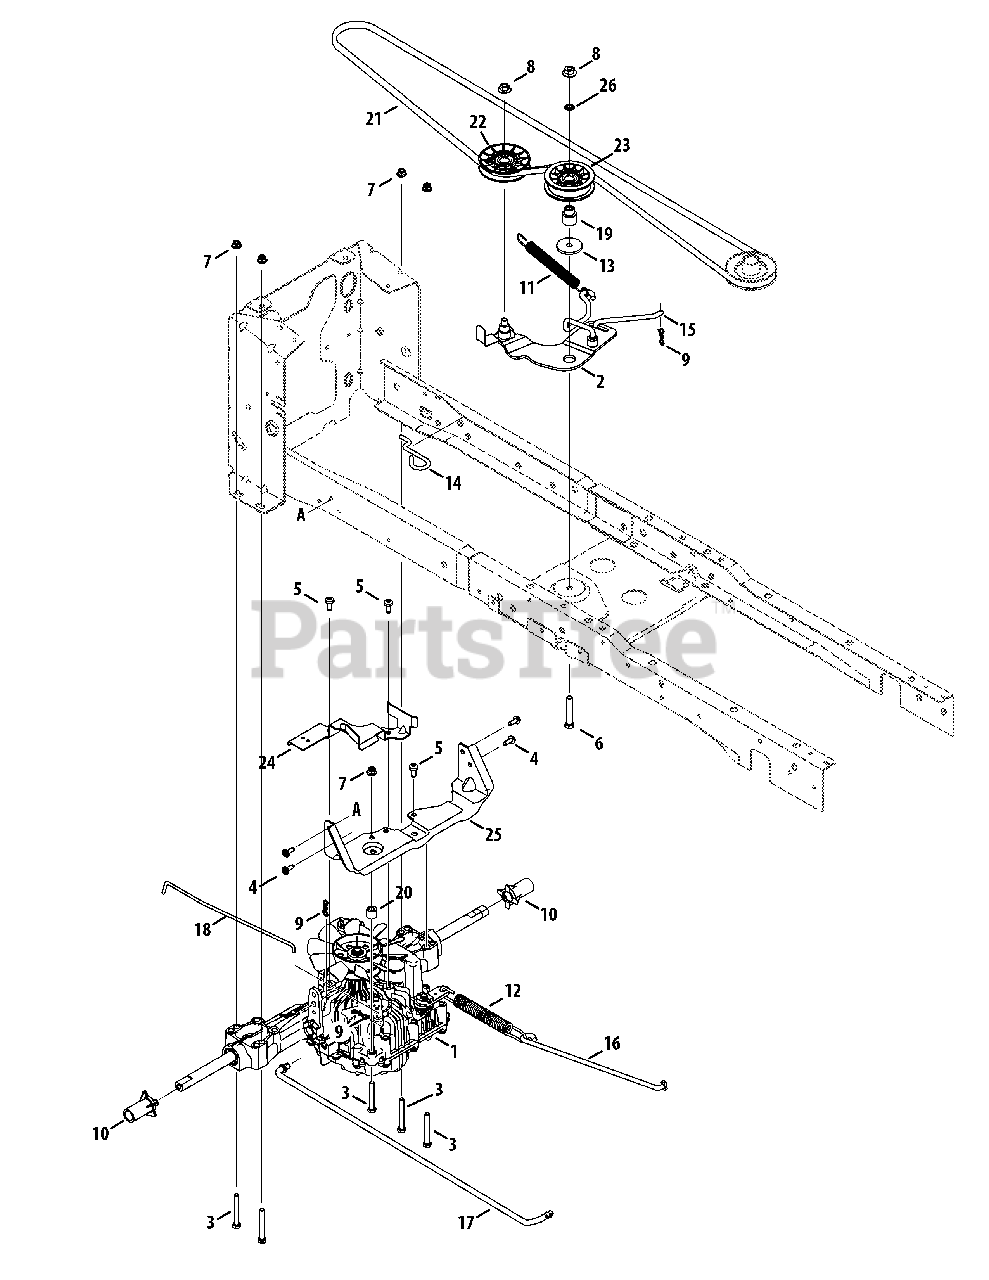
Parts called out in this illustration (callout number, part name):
1	Transmission Assembly
2	Idler bracket Assembly
3	Hex Screw, 5/16-18, 2.50, Gr5, Std
4	Screw, M6-1 x .625
5	Screw, Self-tapping, 5/16-18, 0.750
6	Hex Screw, 3/8-16, 2.25, Gr5
7	Nut, Flange Lock, 5/16-18, Nylon
8	Flange Lock Nut, 3/8-16
9	Pin, Cotter, Bow-Tie 72
10	Sleeve, .765 Id x 2.11
11	Spring, Extension, .790 Dia x 8.41
12	Spring, Extension, .90 Dia x 8.14
13	Shoulder Spacer, .884 x .190
14	Deck Spring Rod
15	Idler Link
16	Rod, Brake, Tuff Torq
17	Rod, Control, Tuff Torq
18	Rod, Transmission, Bypass
19	Shoulder Spacer
20	Spacer, .34 x .75 x .63
21	Belt, V-Type
22	Idler Pulley, 3.56 OD
23	Idler Pulley, 3.00 OD
24	Belt Keeper Bracket
25	Transmission Bracket
26	Speed Nut
